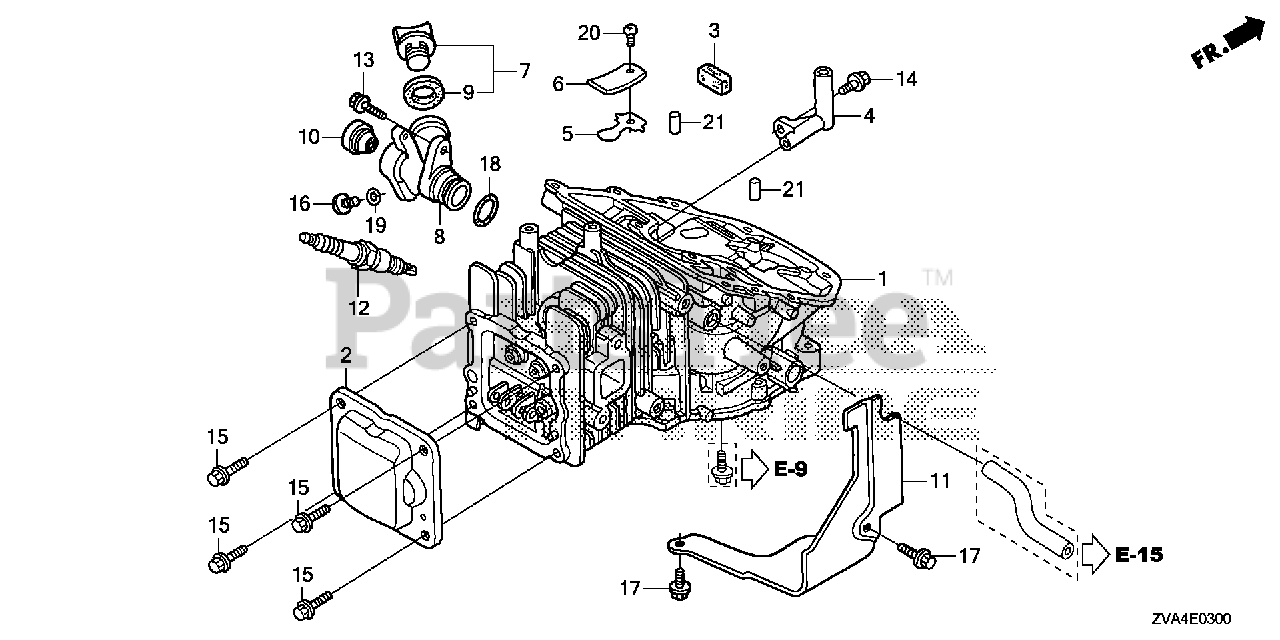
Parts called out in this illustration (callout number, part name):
2	COVER, HEAD
3	FILTER, BREATHER
4	PIPE, BREATHER
5	VALVE, OIL OUTLET
6	PLATE, STOPPER
7	CAP ASSY., OIL FILLER
8	EXTENSION, OIL LEVEL FINDER
9	GASKET, OIL FILLER CAP
10	FINDER, OIL LEVEL
12	SPARK PLUG (LR4C-E) (NGK)
13	BOLT, FLANGE (5X16)
14	BOLT (4X10)
15	BOLT, FLANGE (5X12) (SUS)
16	BOLT, OIL DRAIN
16	BOLT, OIL CHECK
17	BOLT, FLANGE (5X10)
18	O-RING (22.5X2.2) Use from Engine SN 1257295.
19	O-RING (6.9X1.5)
20	SCREW, PAN (3X5)
21	ROLLER (6X14.8)
21	ROLLER (6X15)
